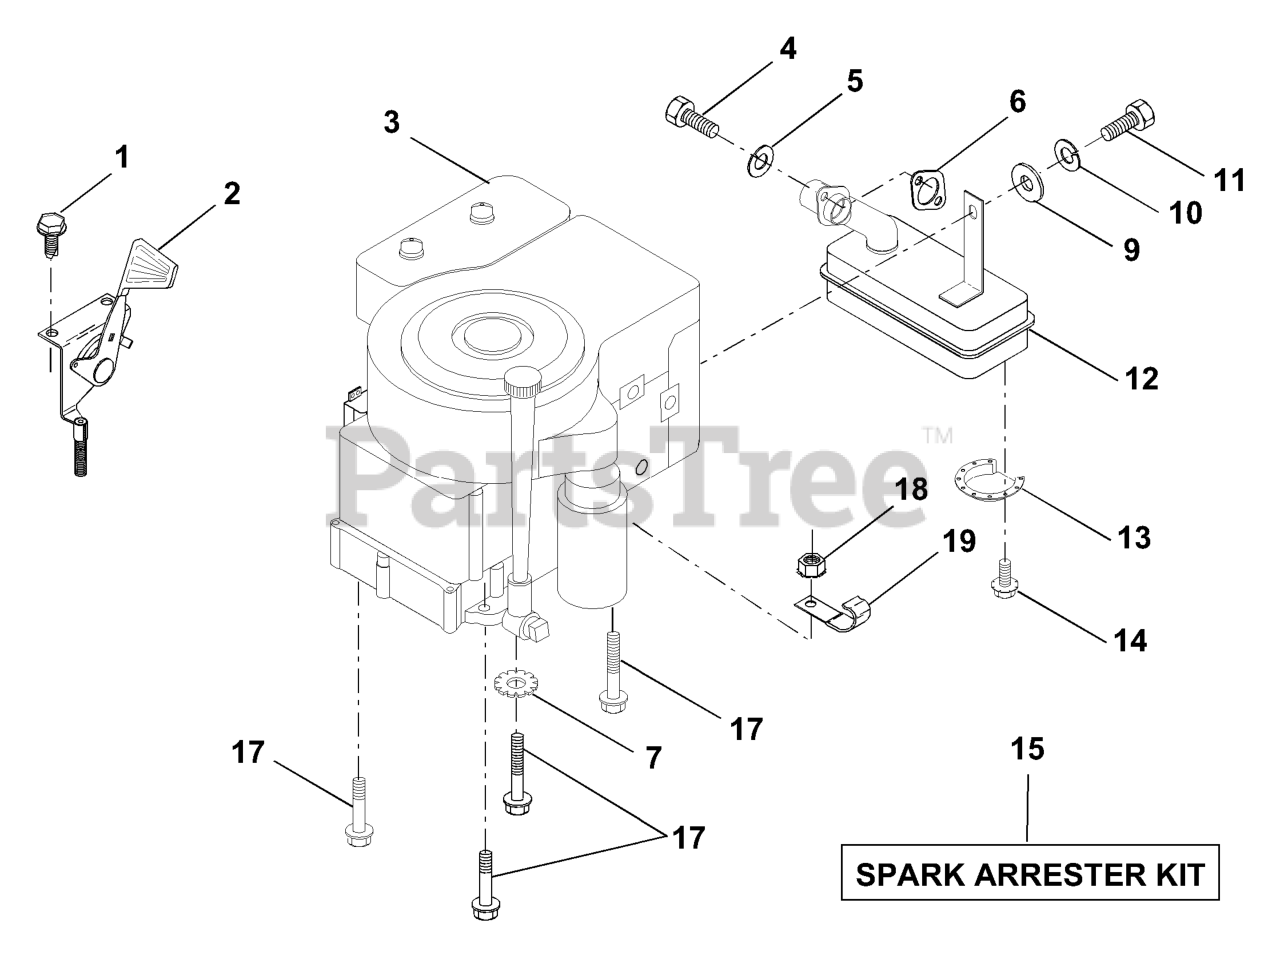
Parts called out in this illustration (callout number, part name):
2	CONTROL.TH/CH.RH.BLK.FLG.26
4	SCREW
5	WASHER.LOCK.HVY.HLCL.SPR.5/16
6	GASKET ENGINE
7	LOCKWASHER
9	WASHER
10	LOCKWASHER
11	Bolt, Hex Fin.
12	MUFFLER.SINGLE.B&S.12HP
13	DEFLECTOR, MUFFLER
14	SCREW
15	KIT.SPARK ARRESTOR 794945 B&S
17	SCREW LT
19	CLIP T
